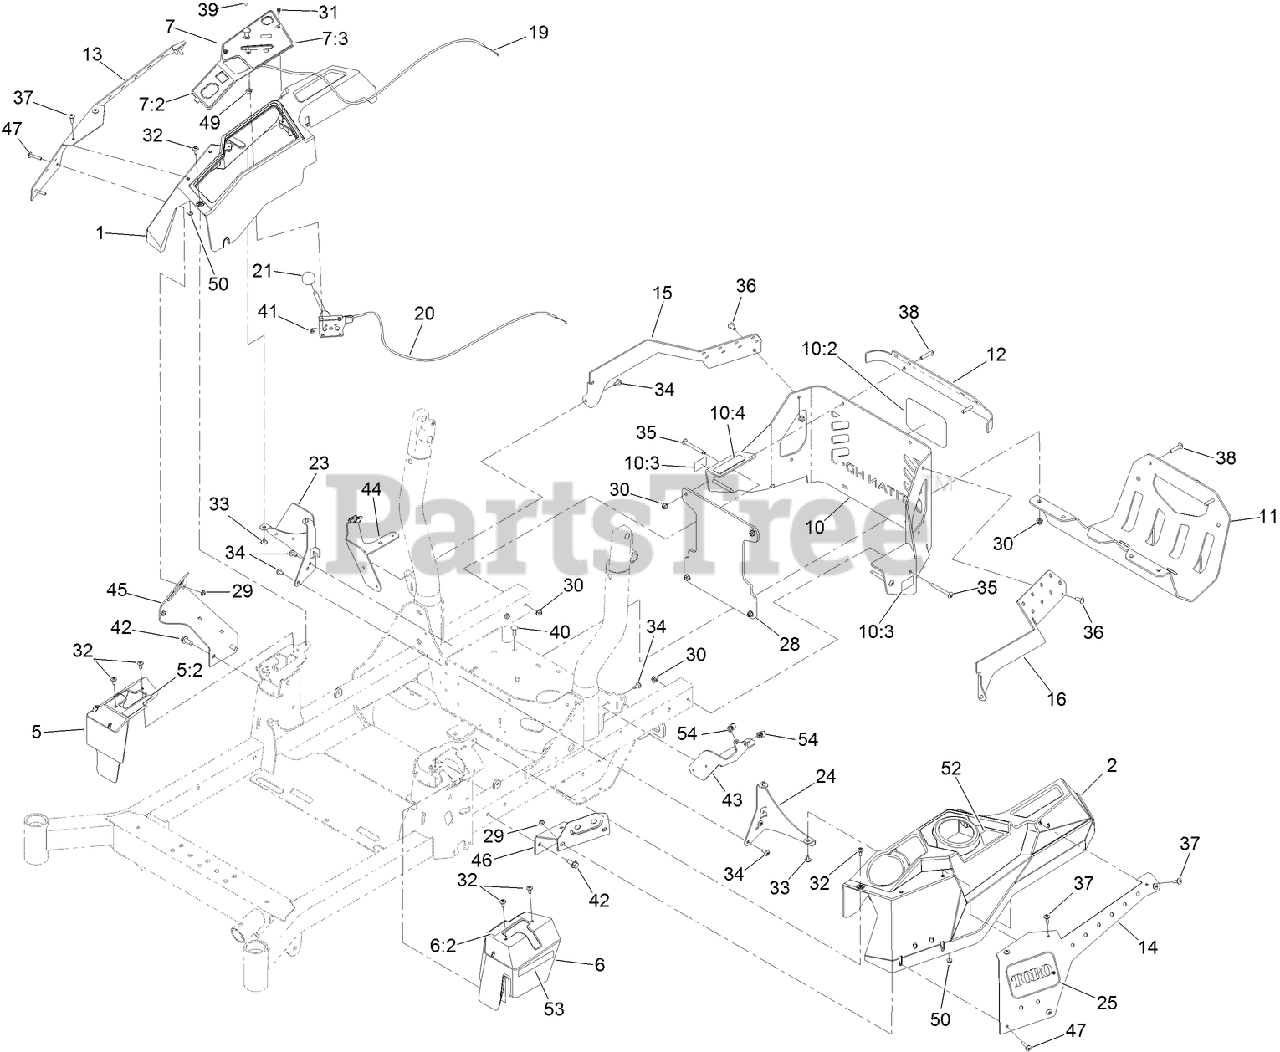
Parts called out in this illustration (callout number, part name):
1	CONSOLE-RH
2	CONSOLE-LH
5	COVER-CONTROL, MOTION (RH)
5:2	DECAL-CONTROL, MOTION (RH)
6	COVER-CONTROL, MOTION (LH)
6:2	DECAL-CONTROL, MOTION (LH)
7	CONTROL PANEL ASM
7:2	DECAL-PANEL, CONTROL
7:3	DECAL-PANEL, CONTROL
10	REAR GUARD ASM
10:2	DECAL
10:3	DECAL-WARNING
10:4	DECAL-ARRESTOR, SPARK
11	GUARD-MUFFLER
12	TRIM-UPPER, REAR
13	COVER-POD, RH
14	COVER-LH
15	BRACKET-GUARD, RH
16	BRACKET-GUARD, LH
19	CABLE-CONTROL, CHOKE
20	CABLE-CONTROL, THROTTLE
21	KNOB-BALL
23	SUPPORT-CONSOLE, RH
24	BRACKET-CONSOLE, LH
25	DECAL
28	WEIGHT-REAR
29	NUT-HF
30	NUT-HF, NI
31	SCREW-HWH
32	SCREW-SHOULDER
33	SCREW-TORX
34	SCREW-TORX
35	SCREW-TORX
36	SCREW-TORX
37	SCREW-TRUSS
38	SCREW-TORX
39	BOLT-CARR
40	SCREW-CARR
41	NUT-LOCK, NI
42	SCREW-FORMING, THREAD
43	BRACKET-SUPPORT, LEFT POD
44	BRACKET-SUPPORT, RIGHT POD
45	BRACKET-SUPPORT, POD (RH)
46	BRACKET-SUPPORT, POD (LH)
47	SCREW-TRUSS
49	NUT-HJ
50	NUT-KEPS
52	DECAL-FILL, FUEL
54	NUT-RETAINER
